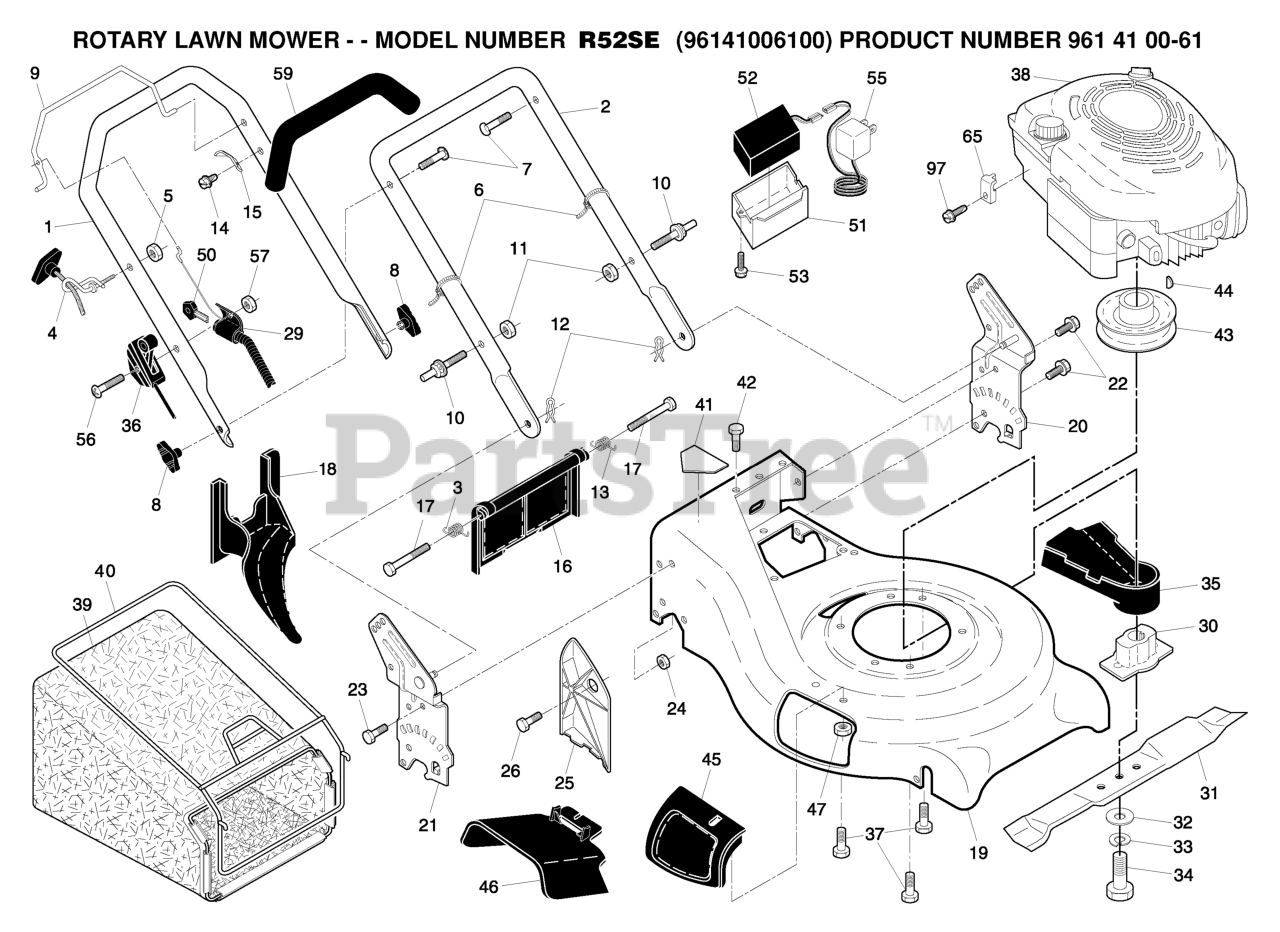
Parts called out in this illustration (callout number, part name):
1	UPPER HANDLE
2	HANDLE.LOWER.21.GREY
3	SPRING.LH.REAR.DOOR.21.RWGD
4	RB GUIDE.ROPE.STD.BLK.ZIN WSL
5	NUT
6	TIE GUIDE
7	BOLT, HANDLE 5/16-18X1.75
11	NUT.CENTERLOCK.5/16-
12	HAIRPIN COTTER
13	SPRING.RH.REAR.DOOR.21.RWGD
15	BRACKET UPSTOP
16	DOOR.REAR.PLASTIC.21.RWGD.BLAC
18	PLUG.MULCHER.RGD.21.
20	BRKT.ASM.HNDL.21.RWGD.LT
21	BRKT.ASM.HNDL
22	SELF-TAPPING SCREW 5/16-18X3/4
23	BOLT, HEX HEAD 5/16-18
24	NUT.71038.31-18.HEX.NYLOCK
25	CLIPPING DEFLECTOR
29	CONTROL.COMBI.KEY.ASMR
30	ADAPTER.BLADE
31	BLADE.21.PUSH
32	WASHER,HARDEN
33	LOCKWASHER
34	SCREW, HEX HD 3/8-24 X 1-3/8
36	CONTRL.THROTTLE.
37	BOLT 3/8-16X1-1/8
40	FRAME.CATCHER.21.RGD.AG
41	DECAL.INTERNATIONL.CUTFINGER
43	PULLEY.ENG.25MMM
44	HI-PRO KEY
45	MULCHER DOOR ASM.
46	DEFLECTOR, DISCHARGE
50	KEY.MOLDED
51	BOX.BATTERY.21RD.,RWGD
52	BATTERY WITH AMP CONECTOR AGM
53	SCREW.HWH.13-16X1.12
55	CHARGER BATTERY CE
56	SCREW 1/4-20 X 2.12
59	GRIP.HANDLE.FOAM
65	CABLE CLAMP(ENGINE)
97	SCREW.HEX.HEAD.WASHER.10-16
